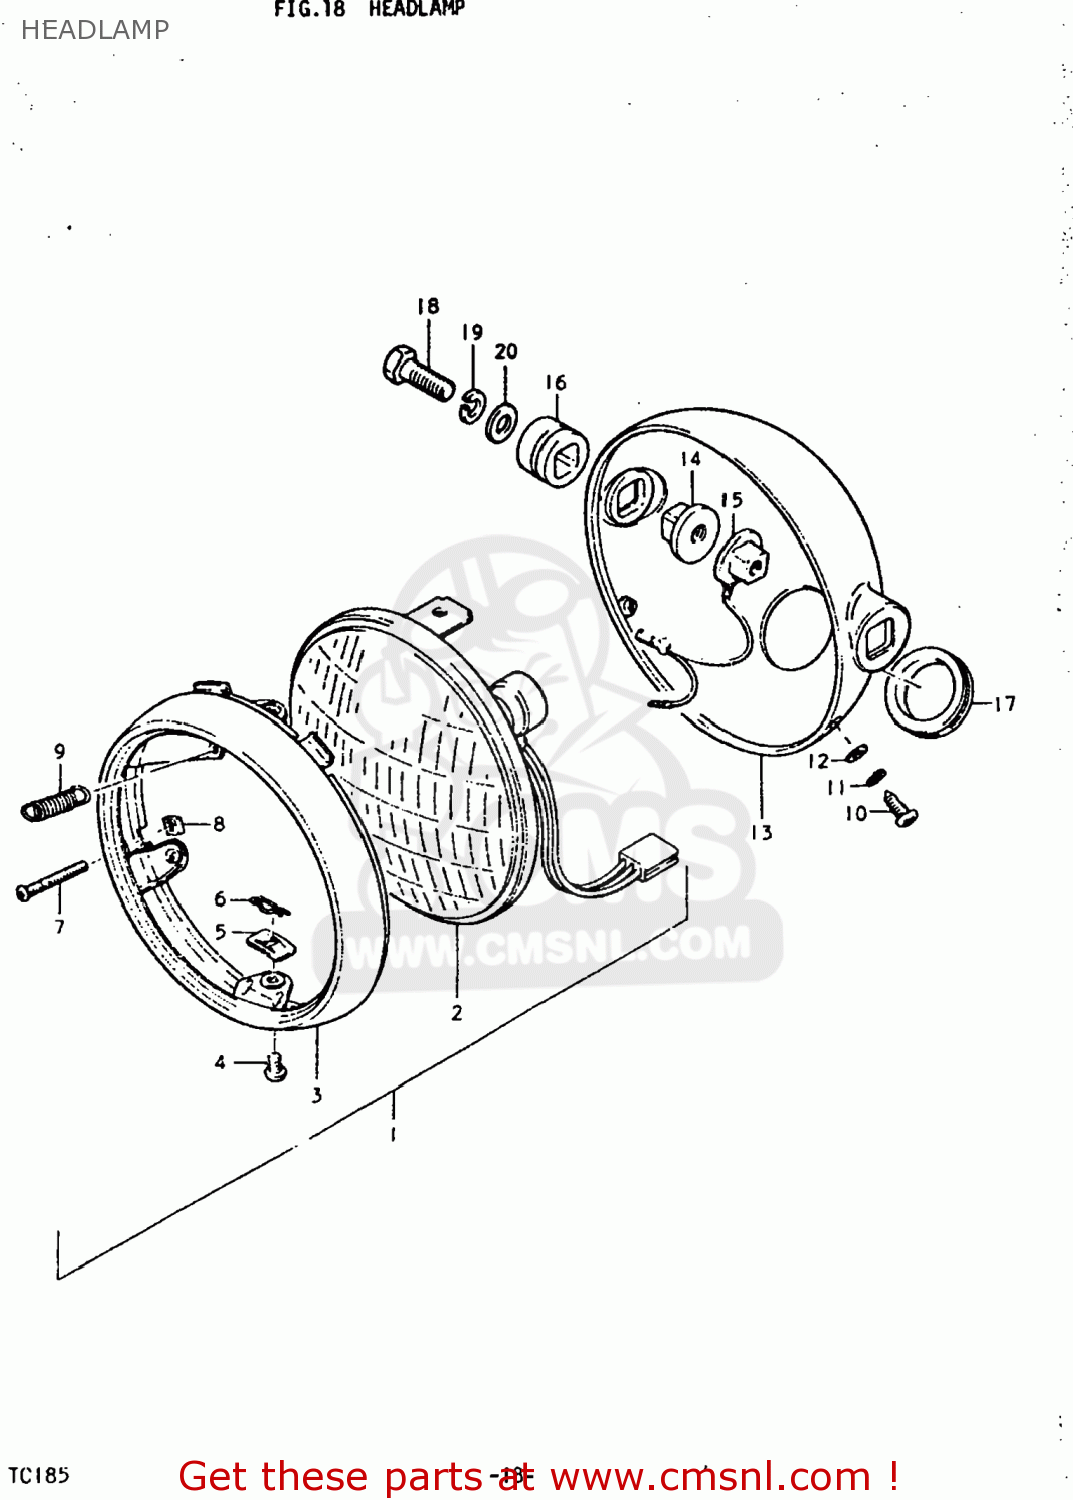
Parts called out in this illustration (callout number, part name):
1	HEADLAMP ASSEMBLY
2	LAMP UNIT
3	RIM,HEADLAMP
4	SCREW
5	NUT,ADJUSTING
6	CUSHION,HEADLAMP
7	SCREW,HEADLAMP ADJUST
8	NUT,HEADLAMP ADJUSTER
9	SPRING,HEADLAMP ADJUST
10	SCREW
11	LOCK WASHER
12	WASHER
13	HOUSING COMP,HEADLAMP
14	SPACER,HEADLAMP HOUSING
15	SPACER,HEADLAMP HOUSING
16	CUSHION,HEADLAMP HOUSING
17	GROMMET,HEADLAMP HOUSING
18	BOLT
19	LOCK WASHER
20	WASHER
